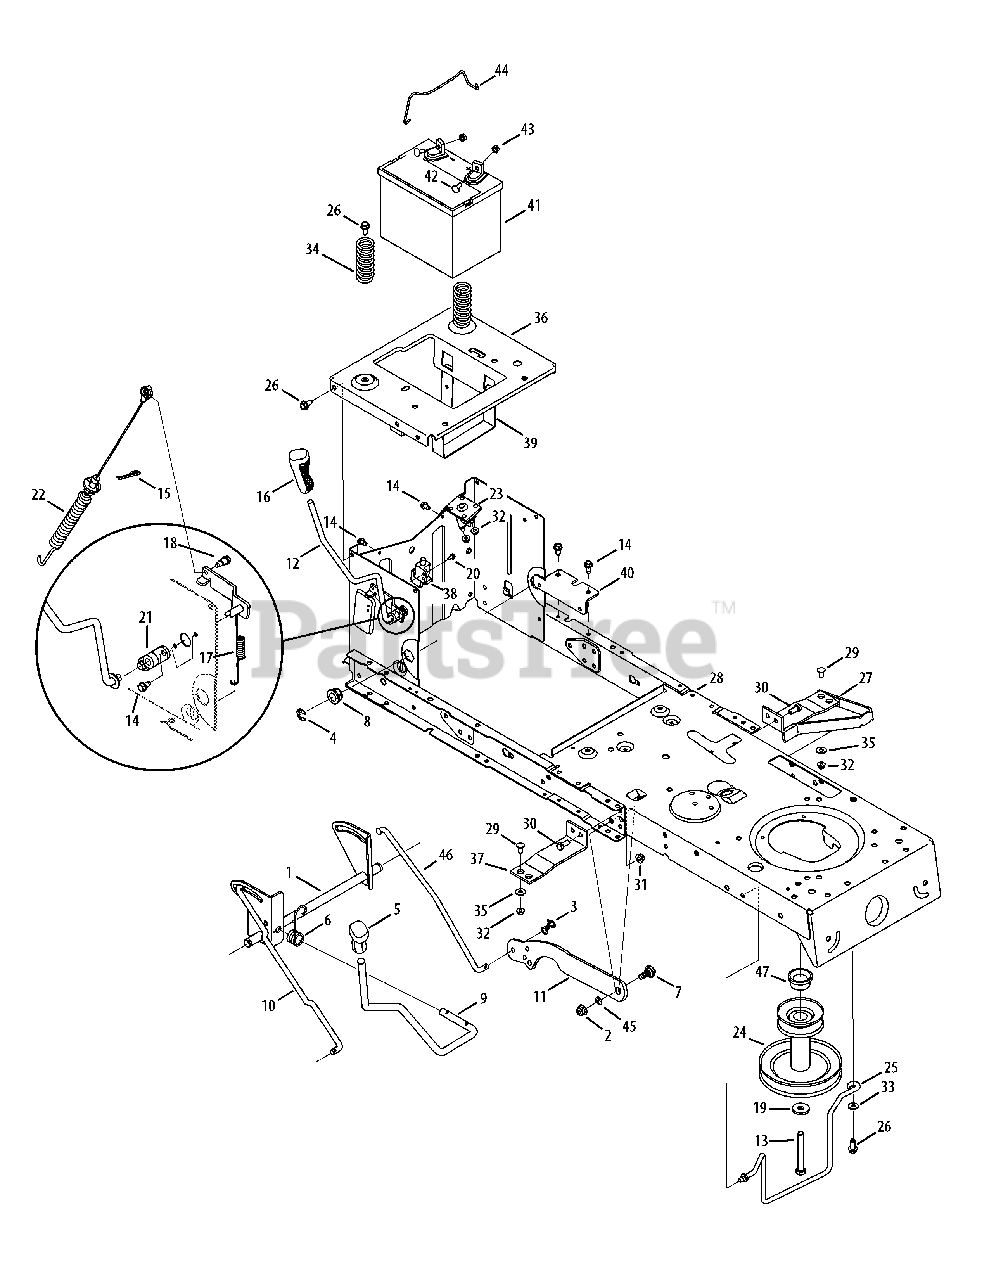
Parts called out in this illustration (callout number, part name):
1	Lift Assembly
2	Nut, Hex Flange Insert Lock, 3/8-16
3	Bow-Tie Pin, 91, RH
4	E-ring, .625 Shaft
5	Grip, Handle
6	Torsion Spring
7	Shoulder Bolt, 3/8-16 x .50 x .270
8	Bearing, Hex Flange,
9	Deck Lift Handle
10	Lift Rod, RH
12	PTO Handle Assembly
13	Screw, Hx. Hd., 7/16-20 x 3.25
14	Screw, Hd. Tapp, 1/4-20 x .5
15	Click Pin
16	Handle Grip
17	PTO Spring, Extension
18	Shoulder Bolt, 1/4-28 x .342 x .335
19	Washer, Flat, .450 x .250 x .164
20	Shoulder Screw, #10-32 x .500
21	PTO Bearing
22	Deck Engagement Cable
23	12v. Solenoid
24	Engine Pulley
25	Belt Keeper Rod Assembly
26	Screw, Hd. Tapp, 5/16-18 x .75
27	Support Bracket Assembly
28	Rider Frame Assembly
29	Carriage Screw, 1/4-20 x .62
30	Screw, Hx. Hd., 5/16-18 x .75
31	Nut, Hex Flange Insert Lock, 5/16-18
32	Nut, Hex Flange Insert Lock, 1/4-20
33	Flat Washer, .406 x .875 x .059
34	Spring, Compress., 1.28 x 3.125
35	Flat Washer, .28 x .74 x .063
36	Seat Bracket Frame
37	Running Board Bracket
38	Interlock Switch
39	Battery Bracket
40	Frame Brace Bracket
41	Battery
42	Screw, Shoulder, .250 x .150
43	Nut, Sems, 1/4-20
44	Battery Rod
45	Flat Washer, .385 x .62 x .063
46	Lift Rod, LH
47	Spacer, 1.010 x 1.400 x .825
